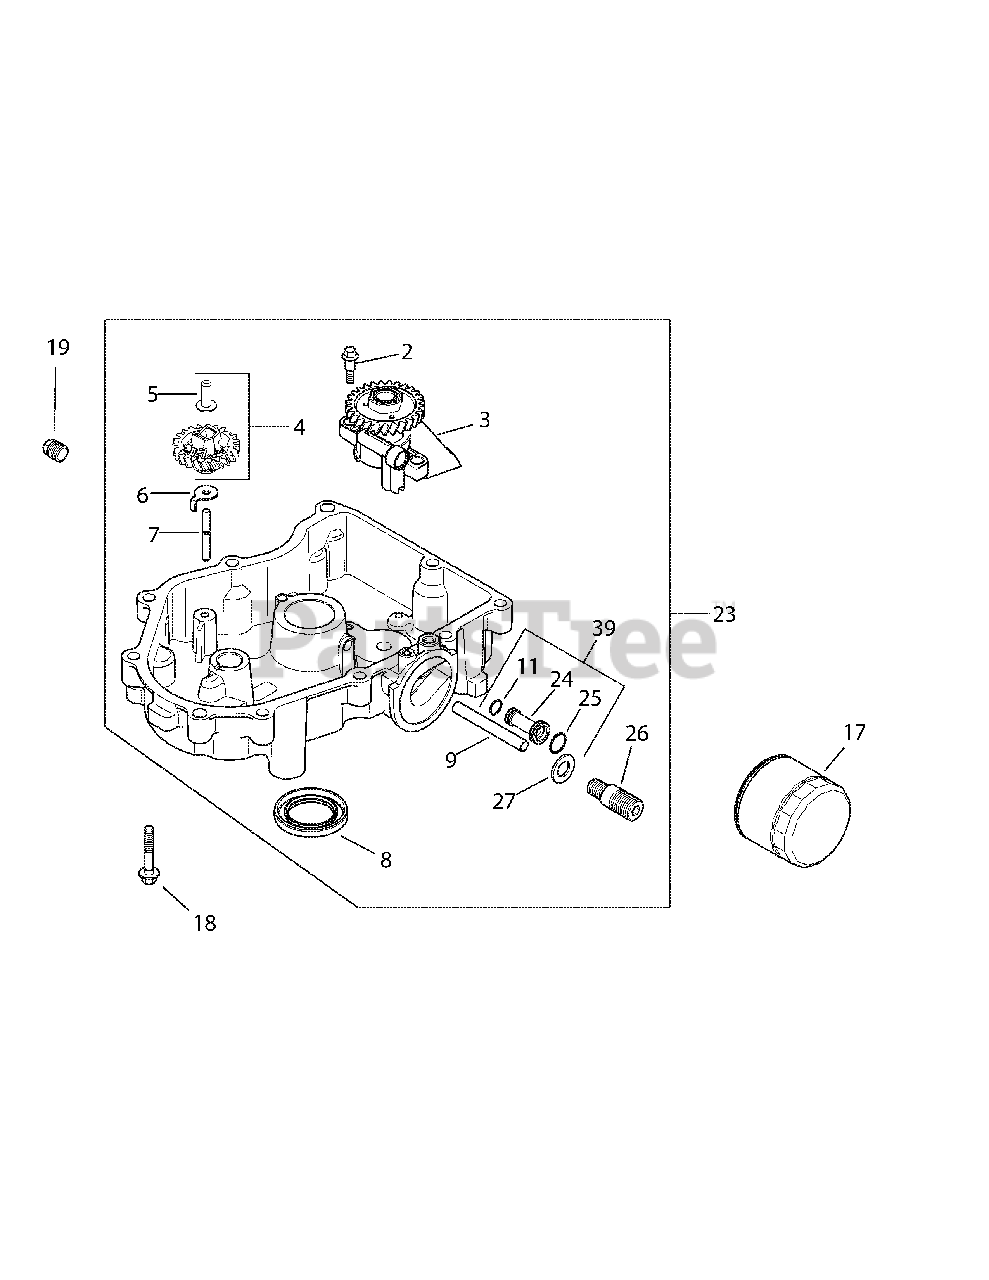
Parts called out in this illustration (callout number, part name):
2	Shd. Thd. Frm. Screw, M6 X .0 X 6.5
3	Oil Pump Assembly
4	Governor Gear w/ Pin Kit (Inc. 5)
5	Governor Regulating Pin
7	Governor Gear Shaft
9	Oil Feed Tube - Filter To Pan
11	Oil Pick-Up O-Ring
13	Plug, Ctsk. Pipe Plug, 1/8
18	Flg. Screw, M8 x 1.25 x 45
19	Sq. Hd. Pipe Plug, 3/8
23	Oil Pan Assembly (Inc. 2-9, 11, 24-27)
24	Oil Feed Tube
26	Oil Filter Nipple
39	Oil Feed Tube Assembly (Includes 11, 24, 25)
